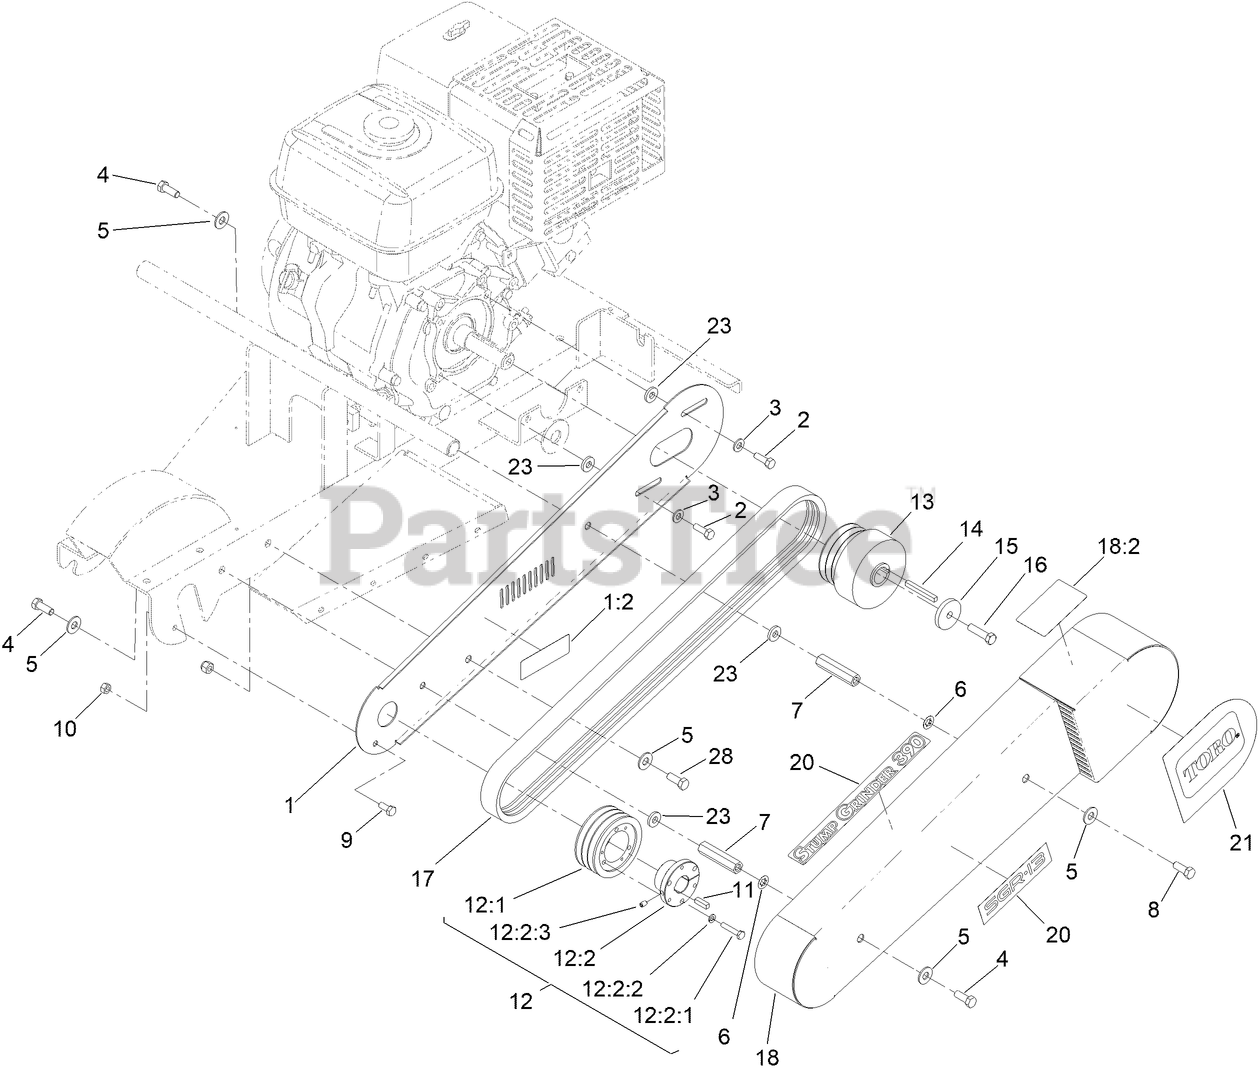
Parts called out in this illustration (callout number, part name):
1	PLATE-GUARD
1:2	DECAL-WARNING
2	SCREW-HH, PATCH
3	WASHER-FLAT
4	SCREW-HH
5	WASHER-FLAT
6	NUT-LOCK, NI
7	SPACER-GUARD
8	SCREW-SET, HSH
9	SCREW-HH
10	NUT-HEX
11	KEY-SQUARE
12	SHEAVE ASM
12:1	PULLEY
12:2	BUSHING
12:2:1	SCREW-HH
12:2:2	WASHER-LOCK
12:2:3	SCREW-SET, HSH
13	CLUTCH
14	KEY-SQUARE
15	WASHER-PLAIN
16	SCREW-HH
17	BELT-3V
18	BELT GUARD ASM
18:2	DECAL-CAUTION
23	SPACER
28	SCREW-HH
